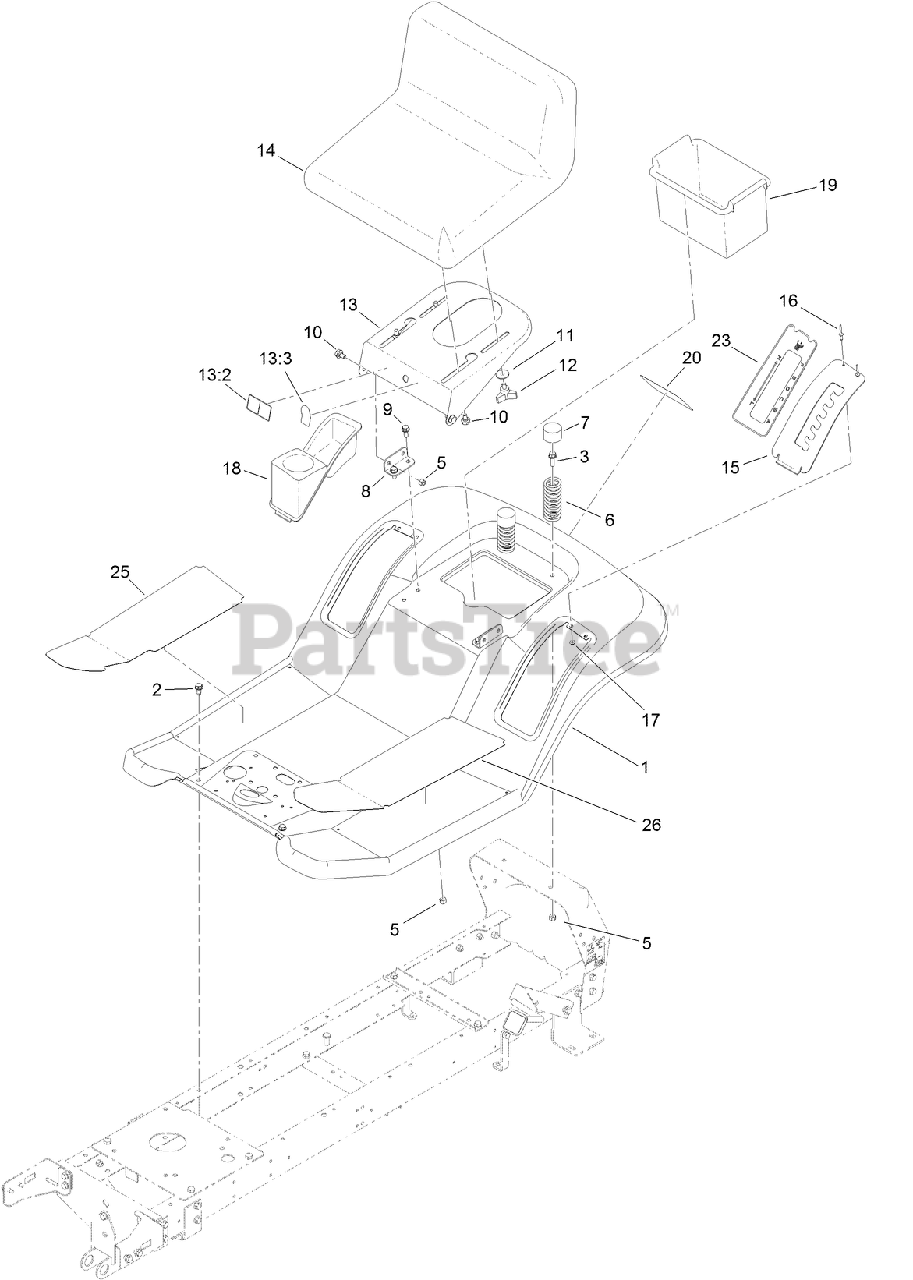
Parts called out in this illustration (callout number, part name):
1	FENDER-BODY, REAR
2	SCREW-HWH
3	SCREW-HHF
5	NUT-LOCK, NI
6	SPRING-COMPRESSION
7	CAP-PROTECTOR
8	BRACKET-PIVOT, SEAT
9	SCREW-HHF
10	BOLT-SHOULDER
11	WASHER-PIVOT
13	SEAT SUPPORT ASM
13:2	DECAL-DANGER
13:3	DECAL-SWITCH
14	SEAT-11 INCH
15	GATE-HOC
16	RIVET-POP
17	WASHER-PLAIN
18	TRAY-FENDER
19	BOX-BATTERY
20	DECAL
23	DECAL-HOC
25	TREAD-FOOTREST, RH
26	TREAD-FOOTREST, LH
